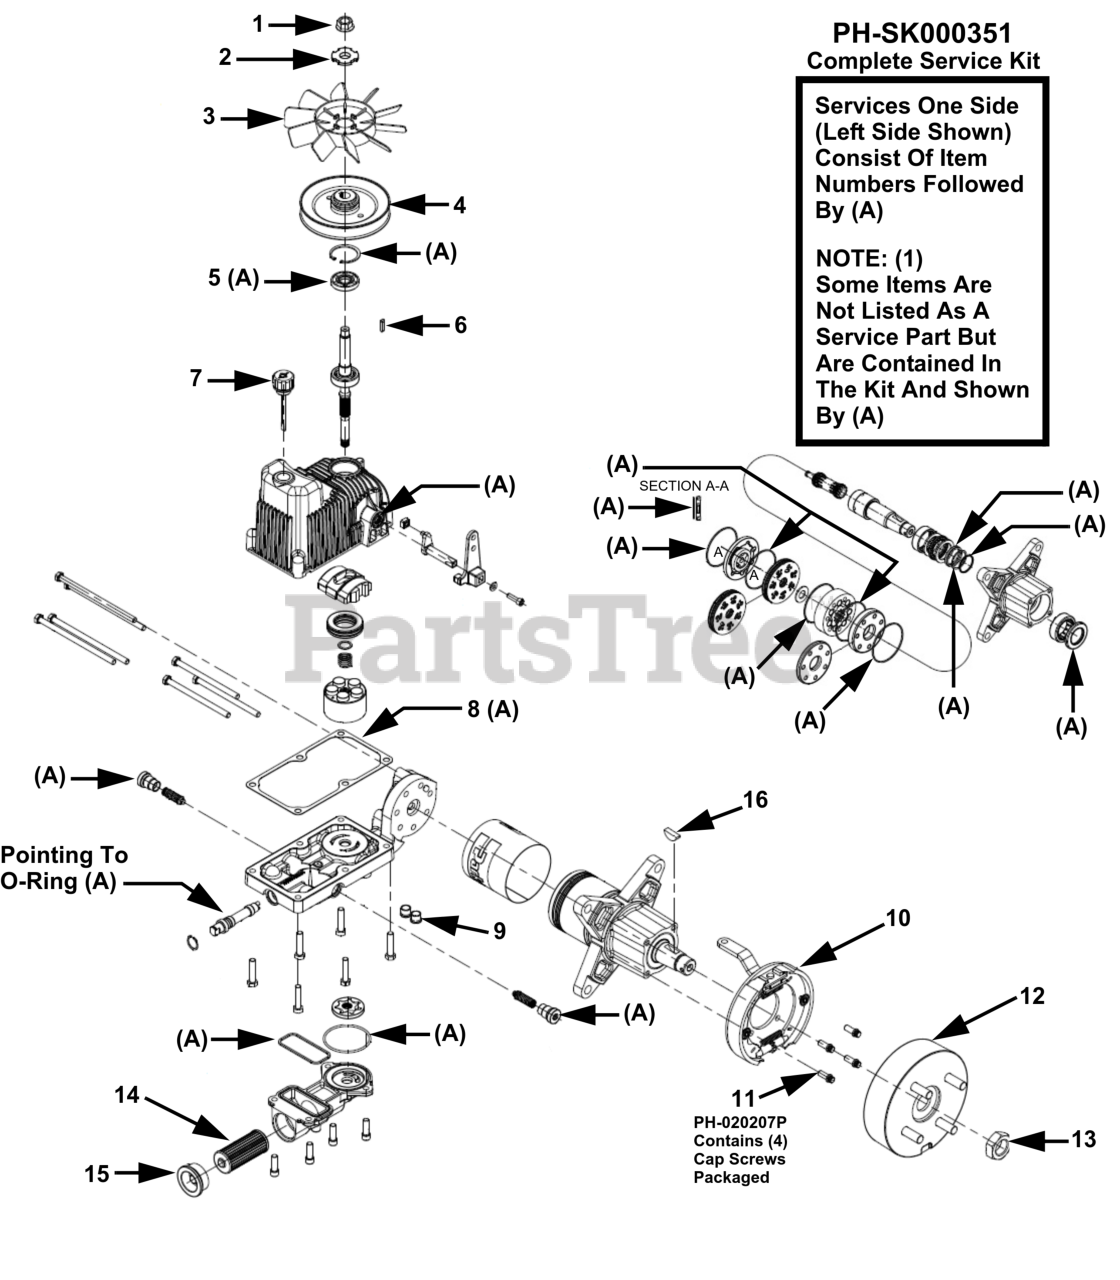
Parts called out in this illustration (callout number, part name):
1	NUT-FLANGE 1/2-20
2	SPACER-FAN
6	SQUARE SHOULDER KEY WAY
7	BREATHER
9	PLUG-MAGNETIC HEX
10	BRAKE ASSEMBLY-ON HOLE LEVER
11	SCREW-CAP (QTY 4)
12	DRUM-4 BOLT BRAKE
13	NUT-SLOTTED
15	PLUG & O-RING ASSE
16	WOODRUFF KEY
17	ROTATING BRACKET
A	COMPLETE SEAL SERVICE KIT
